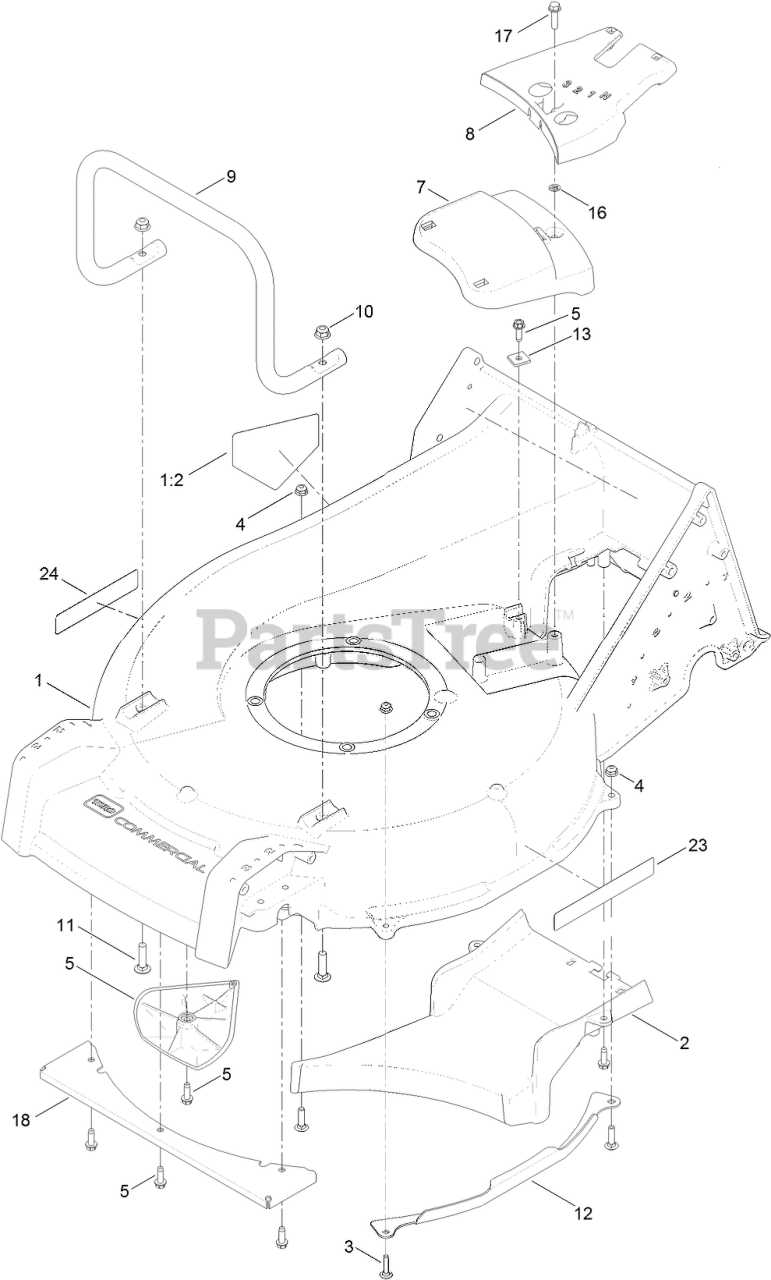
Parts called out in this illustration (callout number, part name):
1	HOUSING ASM
1:2	DECAL-DANGER
2	FLOOR-CHUTE
3	SCREW-CARR
4	NUT-HF
5	KICKER
5	SCREW-HWHTF
7	COVER-BELT, FRONT
8	COVER-BELT, REAR
9	GUARD-ENGINE
10	NUT-HF, NI
11	SCREW-CARR
12	GUARD-SIDE, DECK
13	CLAMP-CABLE
16	NUT-RETAINER
17	SCREW-HWHTF
18	GUARD-TOE, FRONT
23	DECAL-RECYCLER
